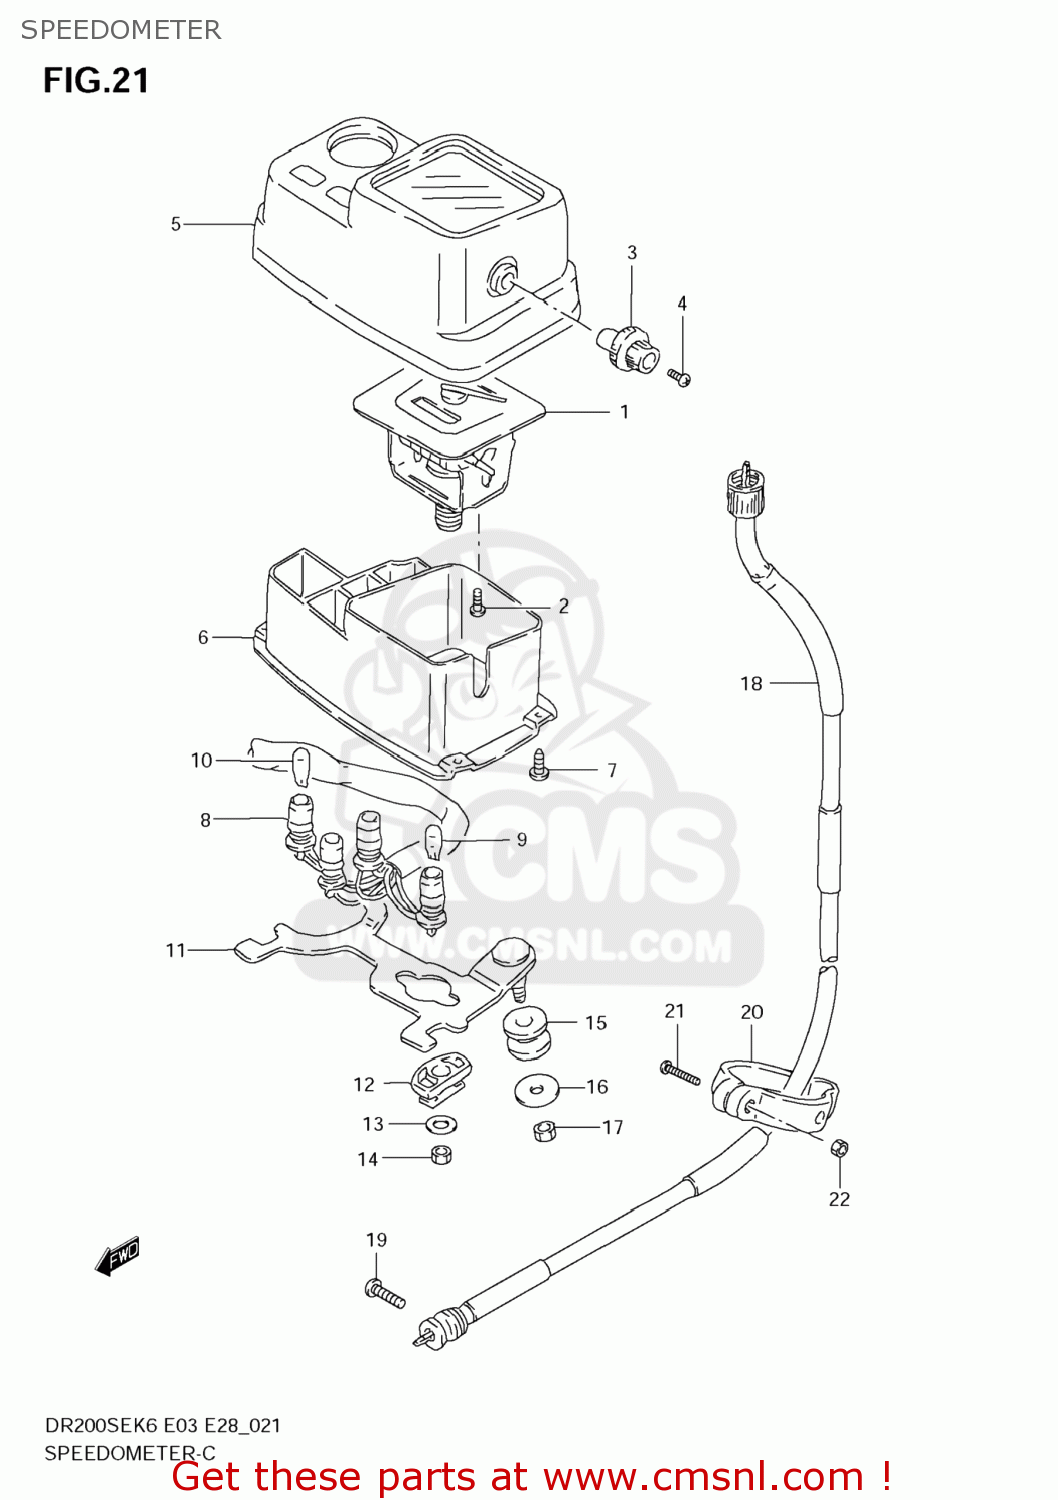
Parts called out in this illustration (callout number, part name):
1	SPEEDOMETER
2	SCREW
3	KNOB,TRIP
4	SCREW(2X6)
5	HOOD,METER
6	CASE,METER
7	SCREW
8	SOCKET ASSY
9	BULB(12V3.4W,T10)
10	BULB(12V1.7W,T10,WB121)
11	BRACKET,METER
12	CUSHION
13	WASHER(5.5X16X1.2)
14	NUT
15	CUSHION
16	WASHER(6.5X18X1.6)
17	NUT
18	CABLE ASSY,SPEEDOMETER
19	SCREW
20	CLAMP,SPEEDOMETER CABLE
21	SCREW
22	NUT
